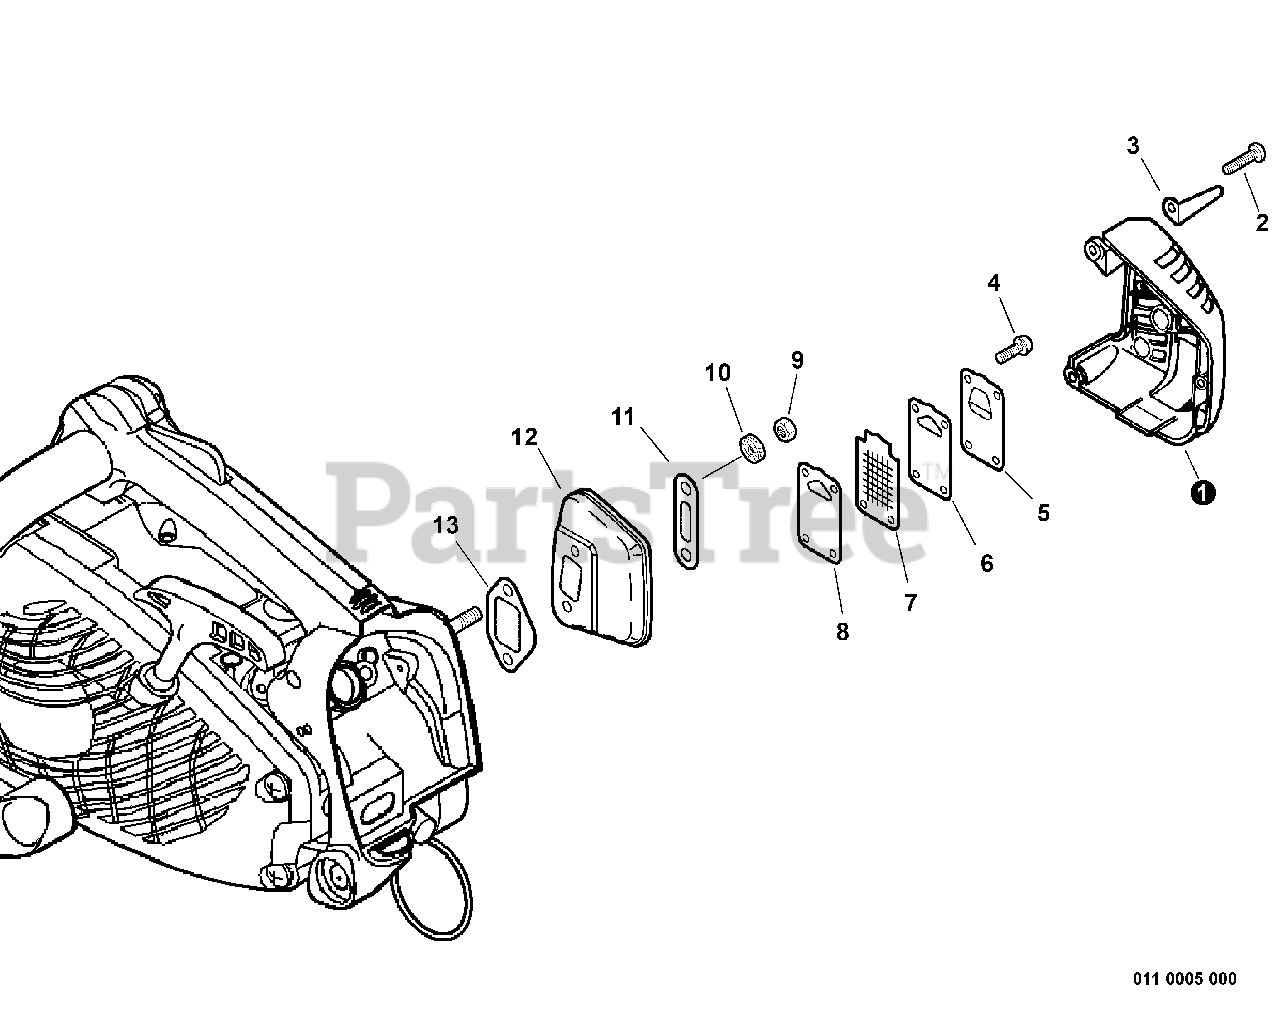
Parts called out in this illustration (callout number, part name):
1	COVER, MUFFLER - GRAY
1	COVER, MUFFLER - ORANGE
2	SCREW 4×16
4	SCREW 4×12
5	OUTLET, EXHAUST
6	GASKET, EXHAUST
7	SCREEN, SPARK ARRESTER
8	GUIDE, EXHAUST
9	NUT M5
11	PLATE, EYE
12	MUFFLER
13	GASKET, EXHAUST
